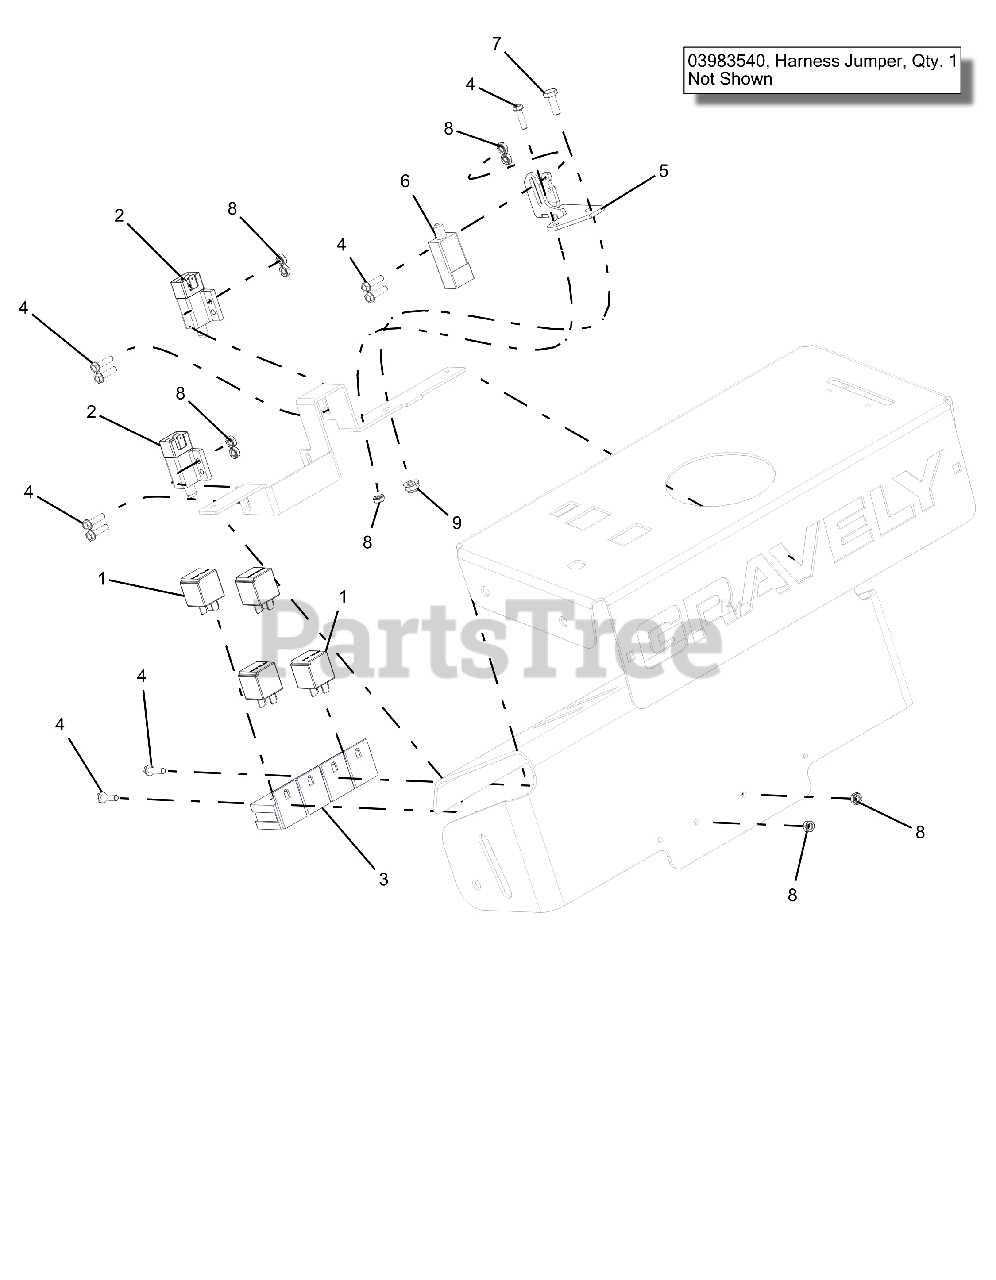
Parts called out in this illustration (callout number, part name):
1	RELAY, ISO MINI ELEC.
2	SWITCH, PLUNGER DP-N.O.-N.C.
3	HARNESS, WIRE MY14 JDCWBM
4	@SCR-MCH 10-24X.75 HWH YWZC
5	WLDMT, SWITCH & SPRING-BLACK
6	SWITCH, INTERLOCK REV C
7	BLT-HEX .25-20X.75 GR5 YWZC
8	NUT-KEPS 10-24
9	NUT-LK-NYL-FLG .25-20 YWZC
10	HARNESS JUMPER
